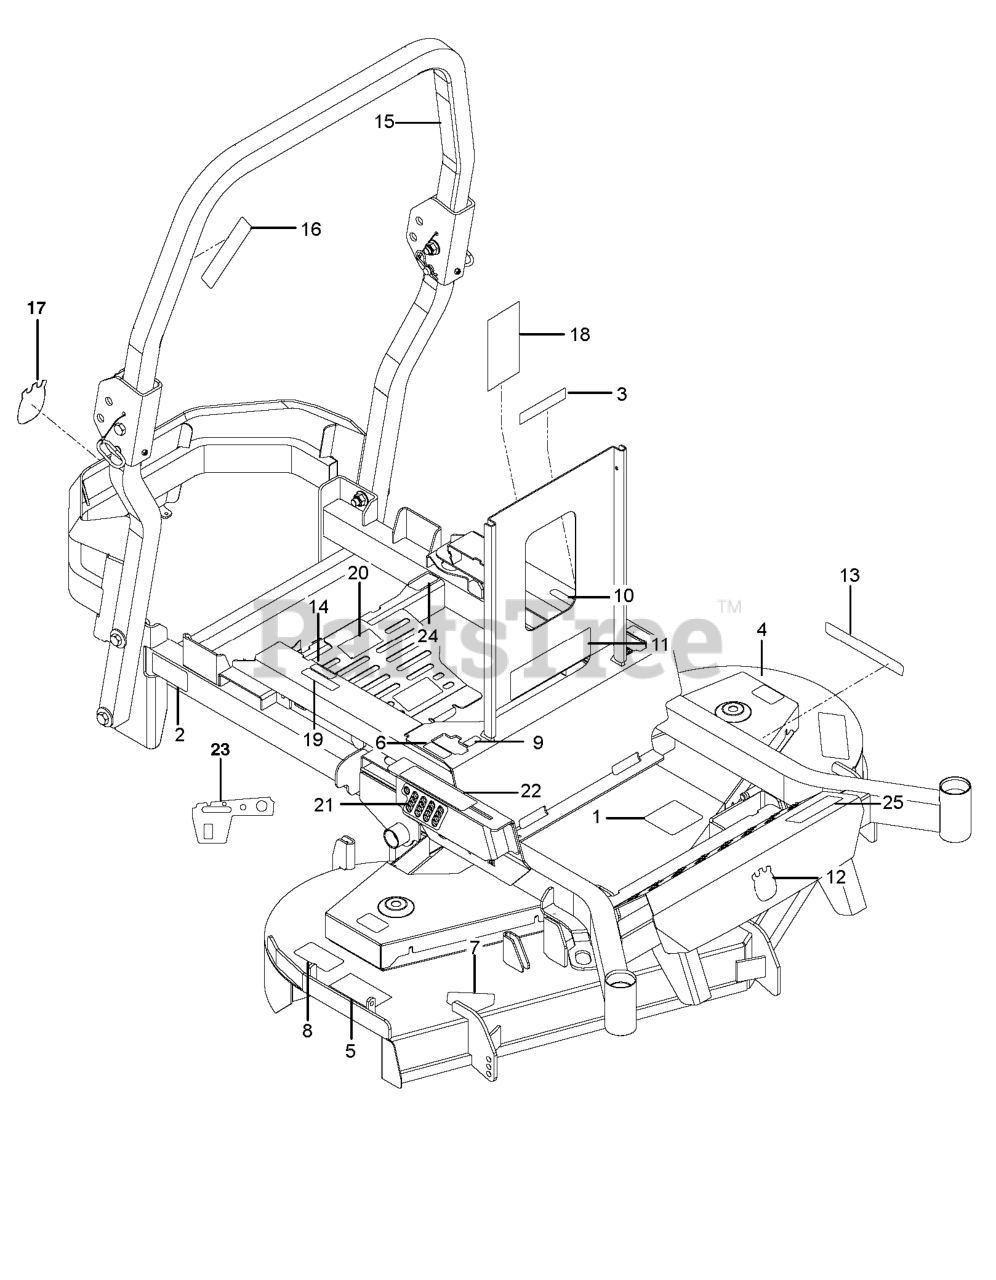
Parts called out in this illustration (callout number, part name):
1	DECAL, BELT ROUTING
2	DECAL, BELT DRIVE
3	EURO DECAL-BATTERY WARNIN6
4	DECAL, NO STEP
5	DECAL, EURO SEVERING
6	DECAL, MOTION CONTROL
7	DECAL, CPSC
8	DECAL, CAUTION
9	DECAL, F.S.T.
10	DECAL, PARK BRAKE
11	DECAL, WARNING
12	DECAL.AUGER.HUSQ.CROWN.SNOW
13	RP.DECAL.BADGE.170MM.TEXTLOGO
14	DECAL, FUSE
15	DECAL, ROPS
16	DECAL, ROPS, WARNING
17	DECAL, CROWN H, 110MM
18	DECAL, SERVICE
19	DECAL, WARNING SPARK ARRESTOR
20	HG_DECAL, ZT-3400
21	DECAL, HEIGHT
22	DECAL, RELEASE LEVER
23	DECAL, CONTROL, GAS
24	DECAL, FUEL
25	DECAL, P-ZT4822
25	DECAL, P-ZT5224
25	DECAL, P-ZT6128
